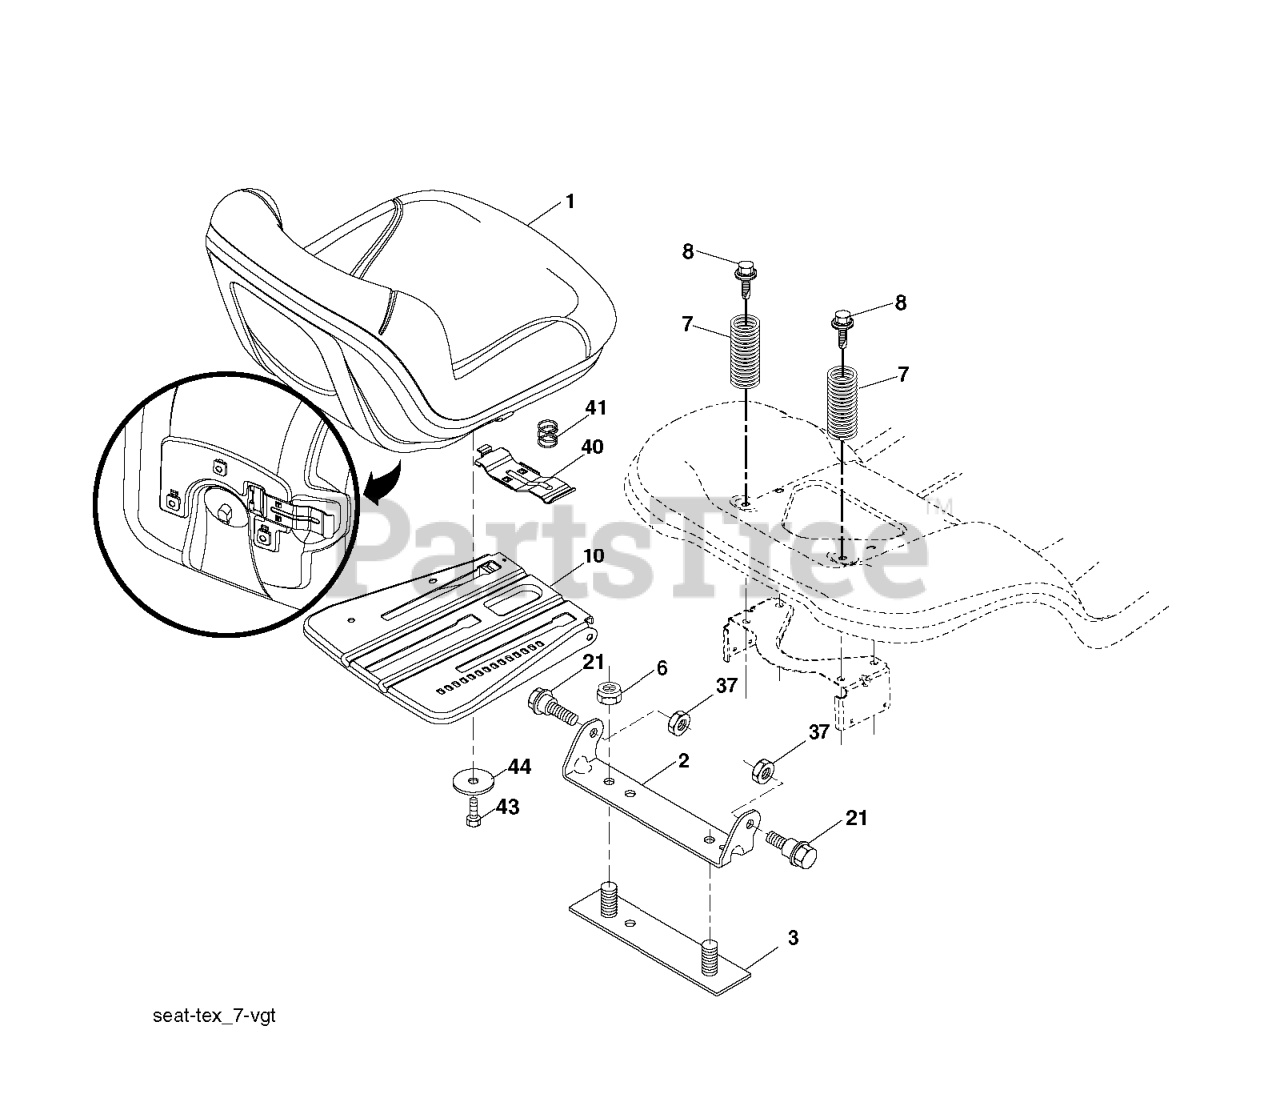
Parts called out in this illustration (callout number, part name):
1	SEAT.TH130.GRY.MILSCO.
2	BRKT.PIVOT.FENDER
3	STRAP
6	NUT
7	SPRING COMPRESSION
8	BOLT.5/16-18UNCX3/4 W/SEMS.BLK
10	PAN.ASM.SEAT.3PT
21	BOLT.SHOULDER.5/16-18
37	NUT.71038.31-18.HEX.NYLOCK
40	HANDLE.SLIDE.SEAT.TEX.BLACK
41	SPRING.LATCH.SEAT.TEX
44	WASHER 13/32 X 2-3/8 X 12GA
